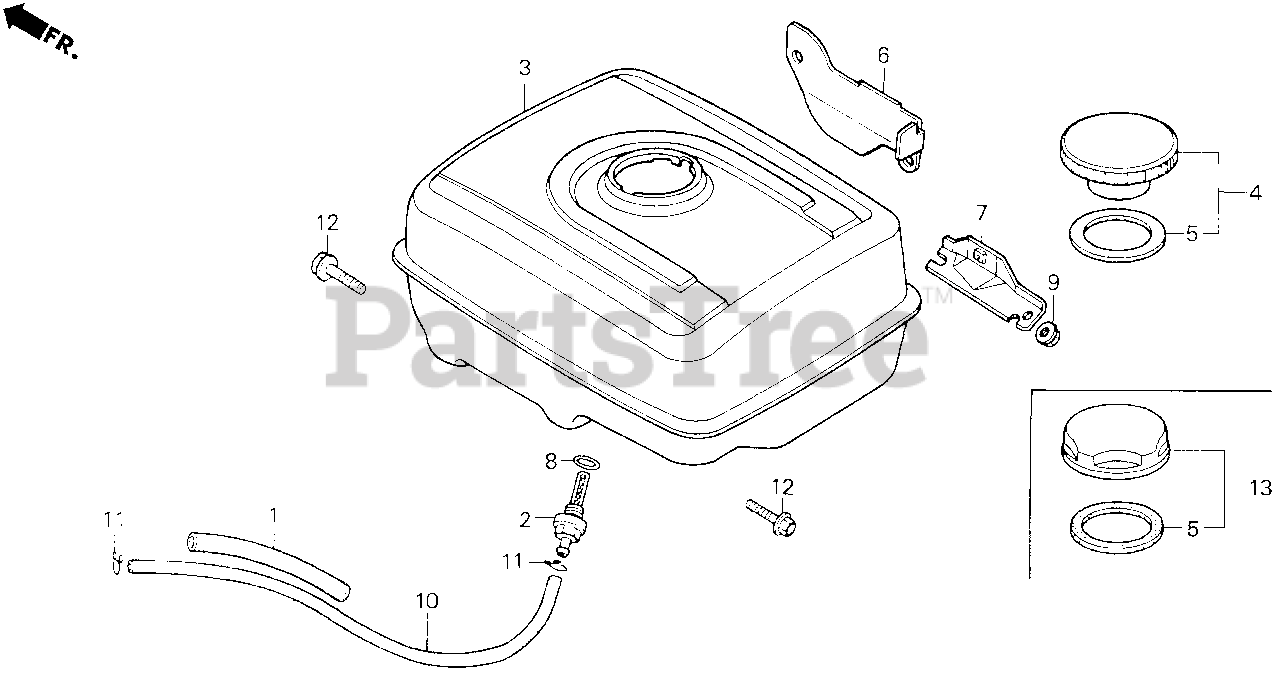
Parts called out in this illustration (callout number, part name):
1	RUBBER, SUPPORTER (107MM)
2	JOINT, FUEL TANK
3	TANK, FUEL *NH31* (MCKINLEY WHITE)
4	CAP, FUEL FILLER
5	GASKET, FUEL FILLER CAP
6	COVER, SNOW PLATE
7	HOLDER, HANDLE BRACKET
8	O-RING (13.5X1.5) (ARAI)
9	NUT, FLANGE (8MM)
10	BULK HOSE, FUEL (4.5X3000) (4.5X222)
11	CLIP, TUBE (B8)
12	BOLT, FLANGE (8X25)
13	CAP, FUEL FILLER
